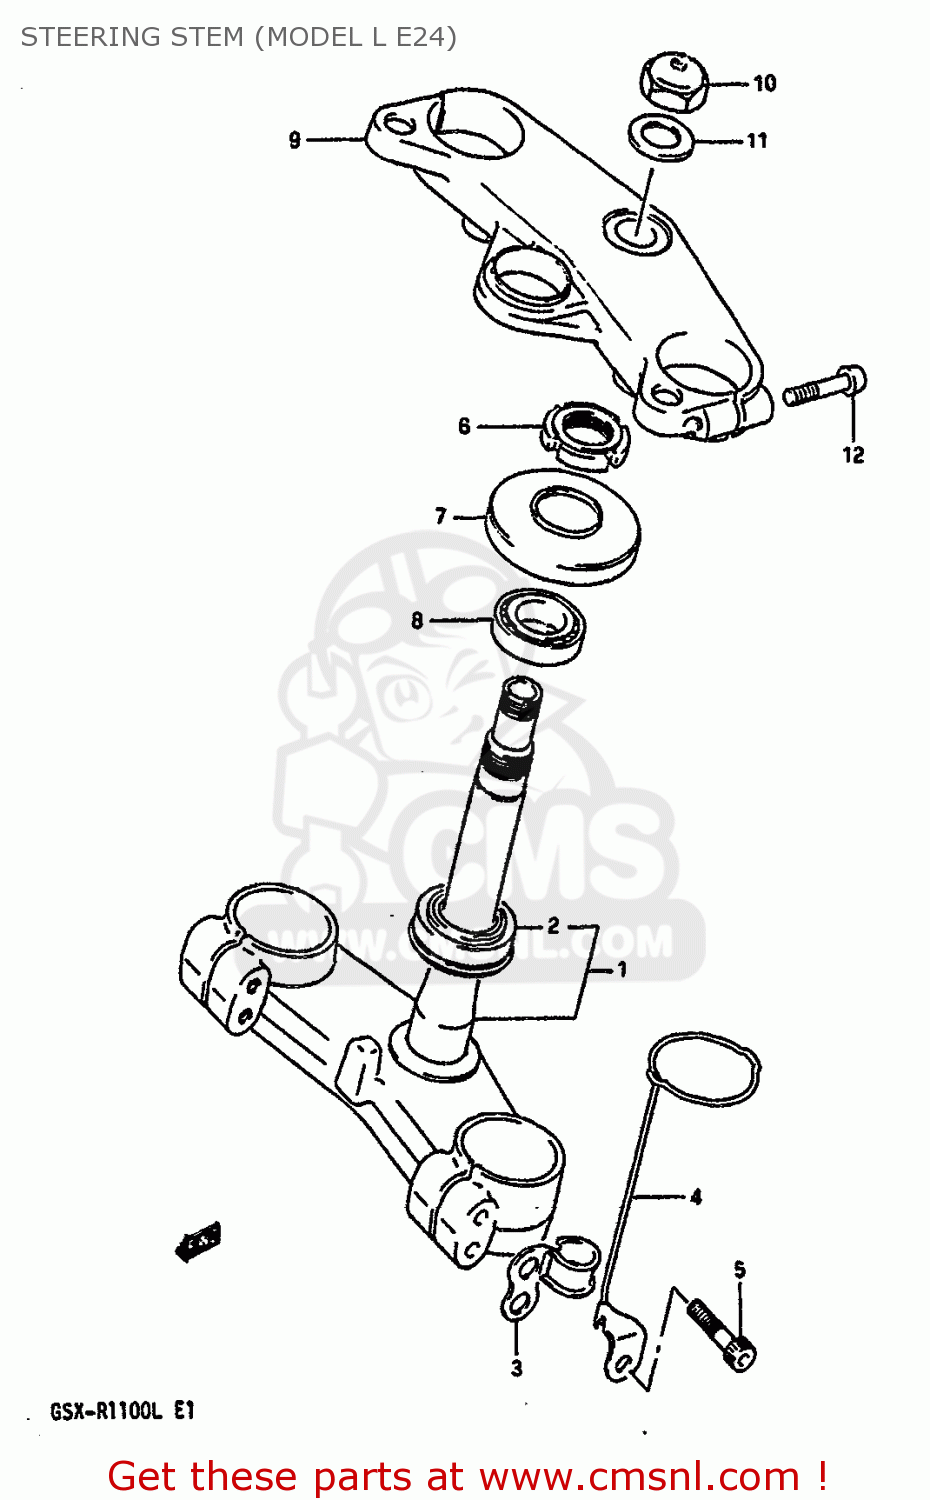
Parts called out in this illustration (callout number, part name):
1	STEM,STEERING
2	BEARING(30X55X17)
3	GUIDE,METER CABLE NO.2
4	HOLDER,STEERING DAMPER
5	BOLT
6	NUT,STEERING STEM(25X44X10)
7	SEAL OIL
8	TAPER,ROLLER BEARING
9	STEM HEAD,STEERING
10	NUT
11	WASHER(22.5X32X1.6)
12	BOLT,FORK INNER TUBE F
